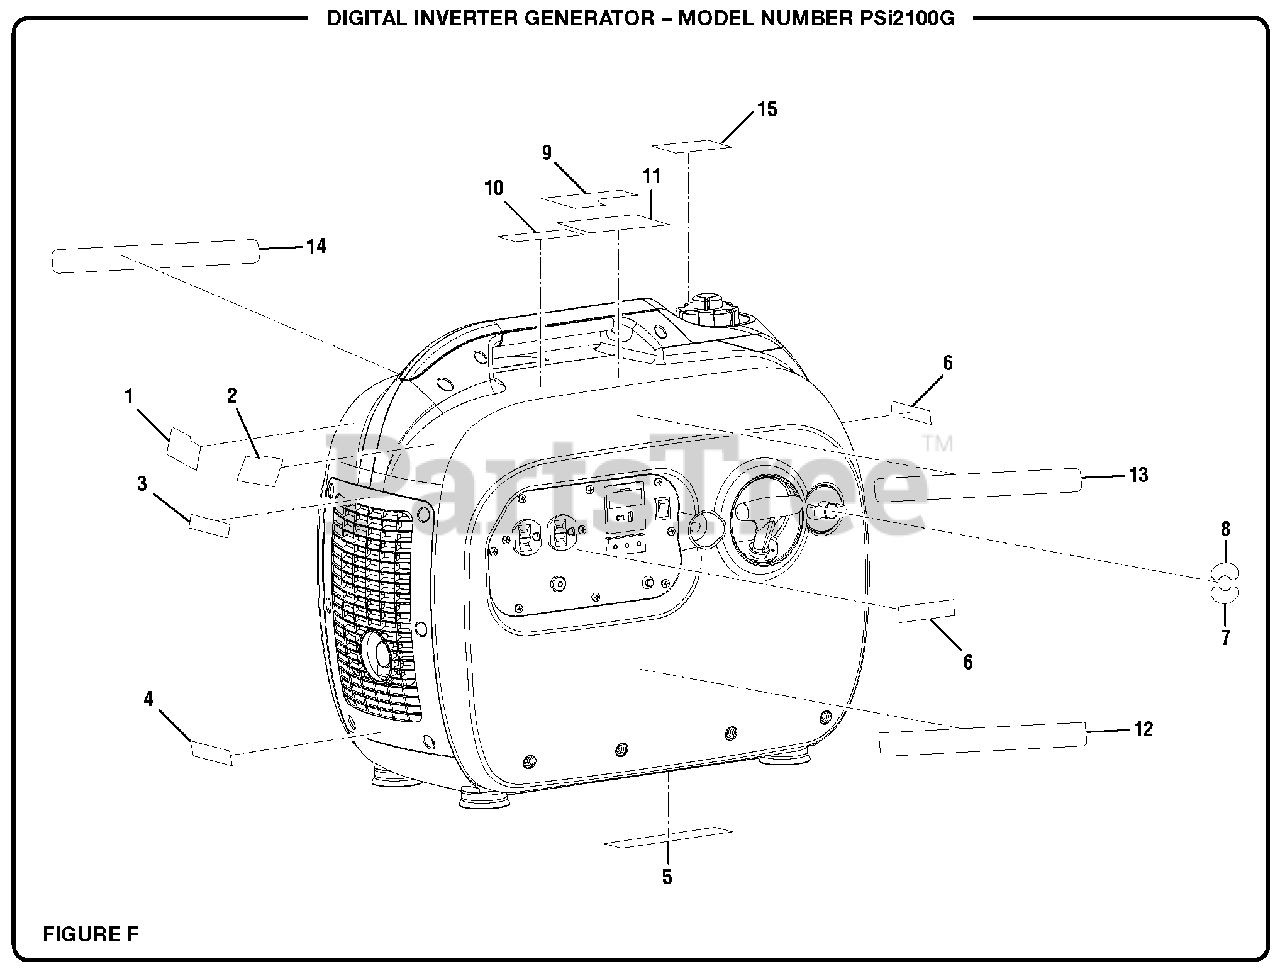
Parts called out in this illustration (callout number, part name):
1	Fire Distance Label
2	Lubricant Label
3	Hot Surface Label
4	Combustion Label
5	Data Label
6	Logo Label
7	"ON" Label
8	"OFF" Label
9	Start Label
10	CPSC Label
11	Danger Icon Label
12	Performance Label
13	Logo Label (Right)
14	Logo Label (Left)
15	Fuel Label (Eng/Sp)
